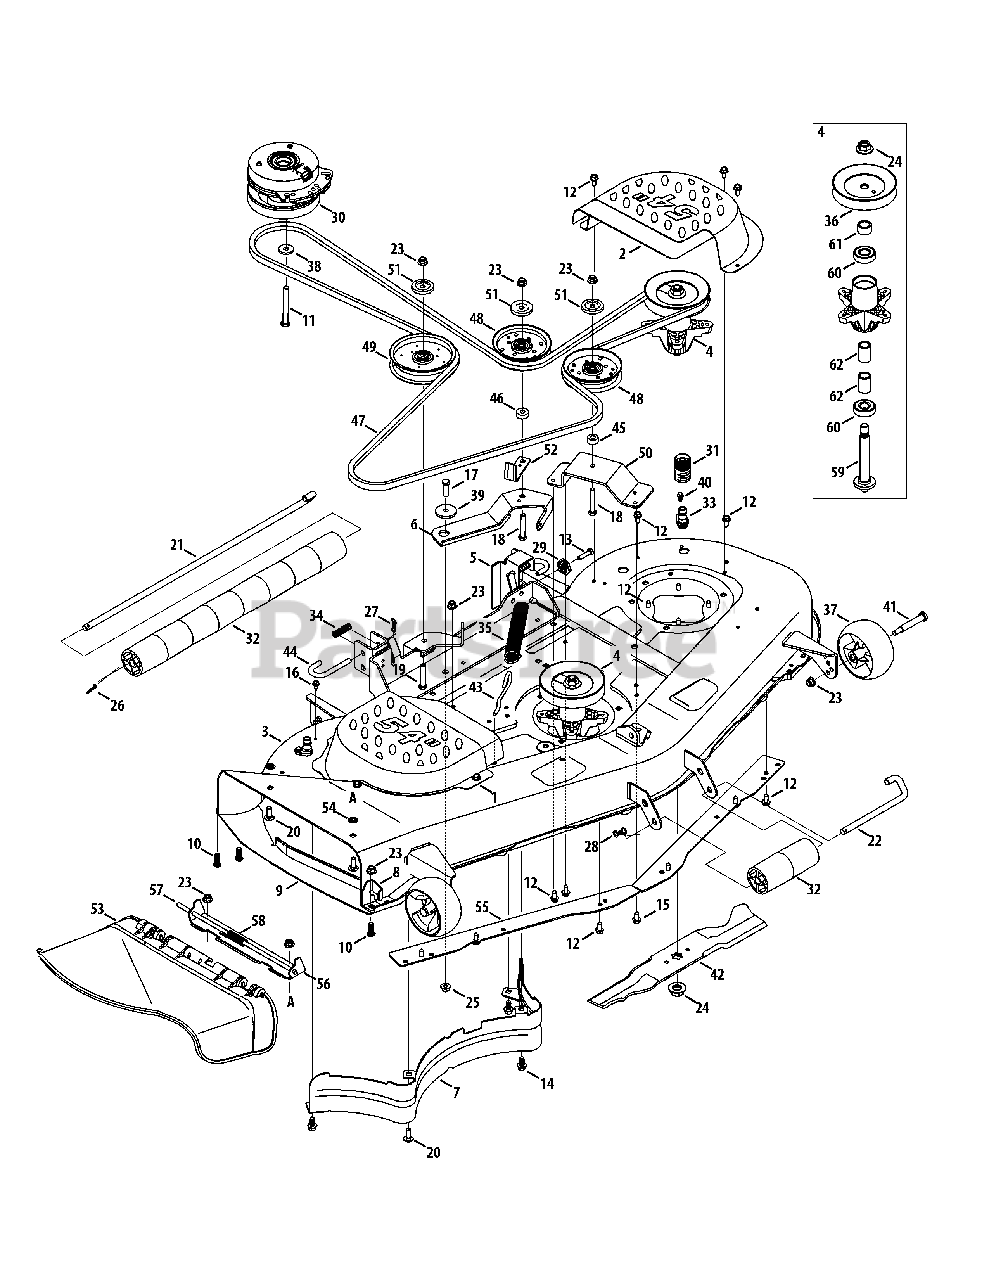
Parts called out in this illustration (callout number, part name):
1	Belt Cover, RH
2	Belt Cover, LH
3	54-Inch Deck
4	Spindle Assembly
5	Deck Lift Bracket
6	Idler Arm
7	Inner Baffle
9	Finger Guard
10	Hex Cap Screw 3/8-16, 1.00
11	Hex Cap Screw 7/16-20 x 3.50
12	Hex Washer Screw 5/16-18 x .750
13	Hex Cap Screw, 5/16-18 x 1.25
14	Hex Washer Screw, 3/8-16 x .75
15	Self Tapping Screw 5/16-18 x .875
16	Hex Washer Screw 1/4-20 x .625
17	Hex Cap Screw 3/8-16 x 1.25
18	Hex Cap Screw 3/8-16, 2.25
19	Hex Cap Screw 3/8-16 x 2.00
20	Carriage Screw 3/8-16 x 1.00
21	J-Hook
22	Roller Pin 1/2-Inch x 7.31 Lg
23	Flange Lock Nut 3/8-16
24	Hex Flange Nut 5/8-18
25	Flange Lock Nut 3/8-16
26	Cotter Pin 5.32 x 1.25
27	Idler Shoulder Spacer
28	Bow-Tie Cotter Pin
29	Deck Adjustment Gear
30	Electric PTO Clutch
31	Water Nozzle Adapter
32	Front Roller
33	Deck Wash Nozzle
34	Compression Spring .66 x 1.9
35	Extension Spring 1.25 OD x 8.5
36	V-Type Pulley 5.39
37	Deck Ball Wheel 5.0
38	Flat Washer .450 x 1.25 x .164
39	Shoulder Spacer .884 x .190
40	Shoulder Screw .500 x 1/4-20
41	Shoulder Screw .5 x 2.5 x 3/8-16
42	Blade, 18.5
43	Deck Spring Rod
44	Deck Hanger Rod
45	Spacer, .385 ID x .875 OD x .458
46	Spacer, .406 ID x 1.00 OD x .380
47	V-Belt
48	Idler Pulley, 4.25 Dia
49	Idler Pulley, 5.00 Dia.
50	Bracket, Idler, Stationary
51	Pulley Cap
52	Belt Guard Bracket
53	Discharge Chute Assembly
54	Push Nut, 3/8
55	Deck Skirt
56	Chute Bracket
57	Hinge Pin
58	Torsion Spring
59	Spindle Shaft, 6.11 Long
60	Ball Bearing
61	Spacer, .82 x 1.15 x .69
62	Spacer, .792 x 1.06 x 1.52
